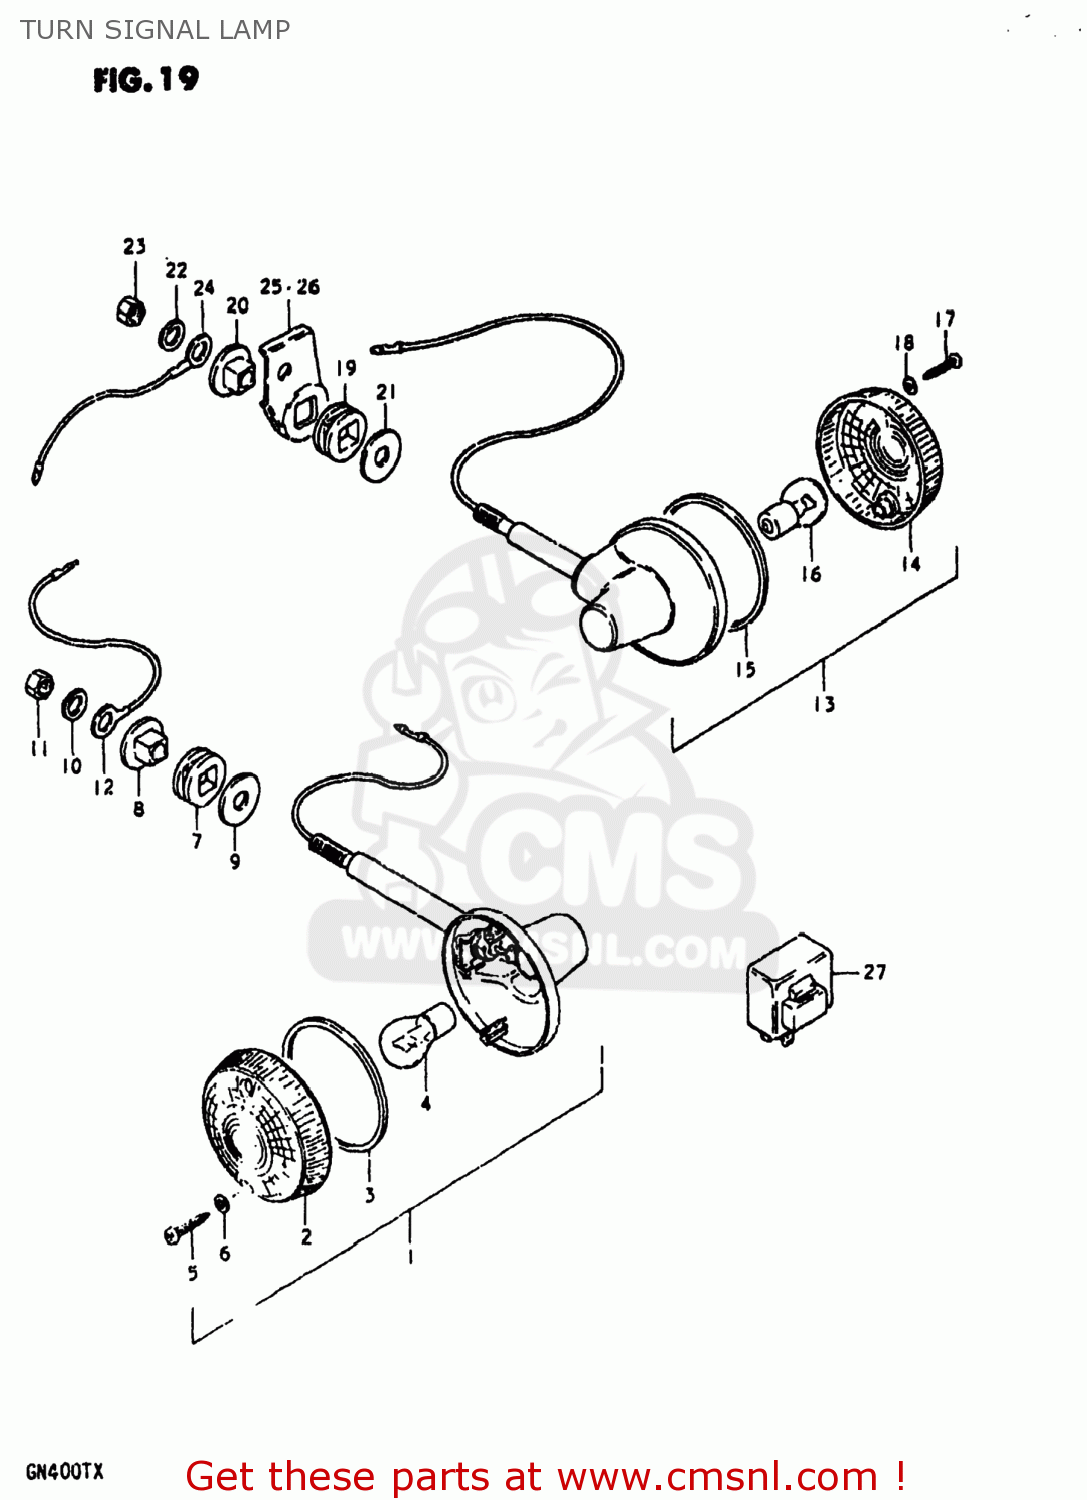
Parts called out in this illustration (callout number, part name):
1	LAMP ASSEMBLY,FRONT TURN SIGNAL
2	LENS
3	GASKET (NAS)
4	BULB(6V17W,STANLEY,A4513A)
5	SCREW
6	GASKET (NAS)
7	CUSHION
8	SPACER,TURN SIGNAL LAMP
9	WASHER (10.5X30X2.3)
10	LOCK WASHER
11	NUT
12	LEAD WIRE,EARTH
13	LAMP ASSEMBLY,REAR TURN SIGNAL
14	LENS
15	GASKET (NAS)
16	BULB(6V17W,STANLEY,A4513A)
17	SCREW
18	GASKET (NAS)
19	CUSHION
20	SPACER,TURN SIGNAL LAMP
21	WASHER (10.5X30X2.3)
22	LOCK WASHER
23	NUT
24	LEAD WIRE,EARTH
25	BRACKET,RR TURNSIGNAL LAMP,R
26	BRACKET,RR TURNSIGNAL LAMP,L
27	RELAY,TURN SIGNAL
